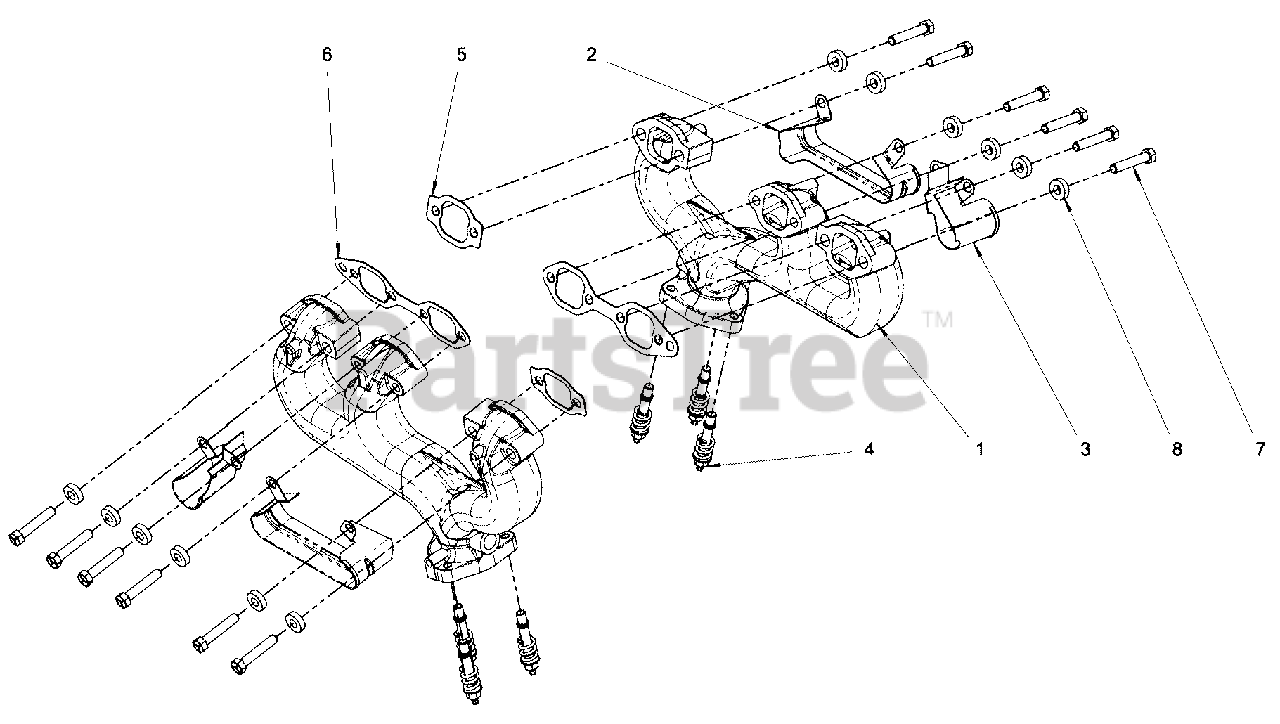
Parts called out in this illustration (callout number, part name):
1	MANIFOLD, EXHAUST
2	SHIELD, HEAT
3	SHIELD, SPARK PLUG WIRE
4	KIT, EXHAUST
5	GASKET, E/MNFLD
6	GASKET, EXHAUST MANIFOLD
7	BOLT
8	WASHER
